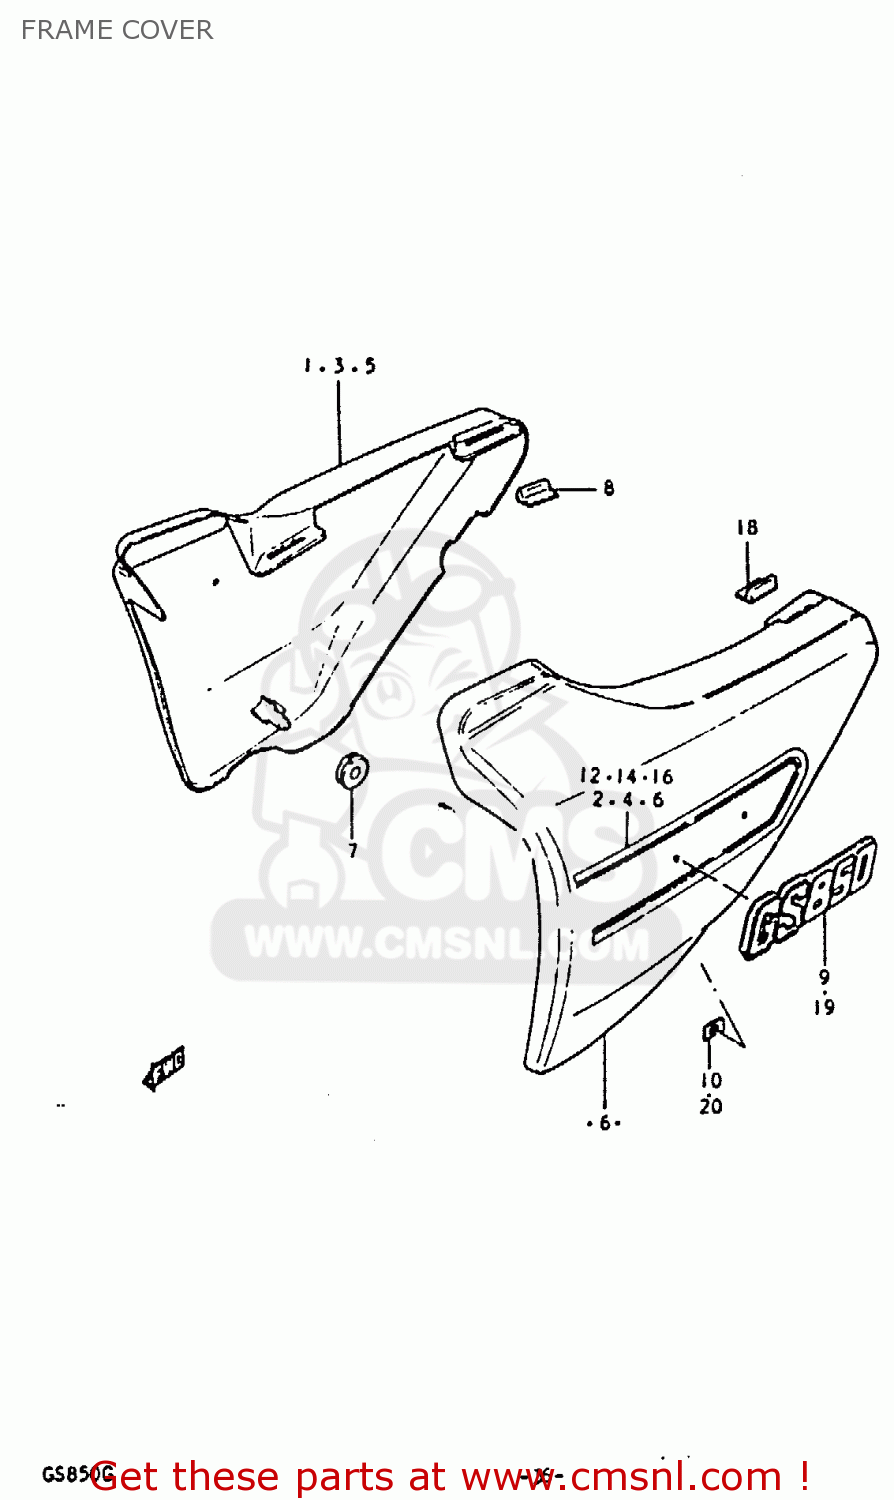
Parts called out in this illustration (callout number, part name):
1	COVER,FRAME,RIGHT
2	TAPE, RH
3	COVER, FRAME RH
4	TAPE, RH
5	COVER, FRAME RH
6	TAPE, RH
7	CUSHION
8	CUSHION,FRAME COVER
9	EMBLEM,FRAME COVER
10	NUT
11	COVER,FRAME,LEFT
12	TAPE, LH
13	COVER, FRAME LH
14	TAPE, LH
15	COVER, FRAME LH
16	TAPE, LH
17	CUSHION
18	CUSHION,FRAME COVER
19	EMBLEM,FRAME COVER
20	NUT
